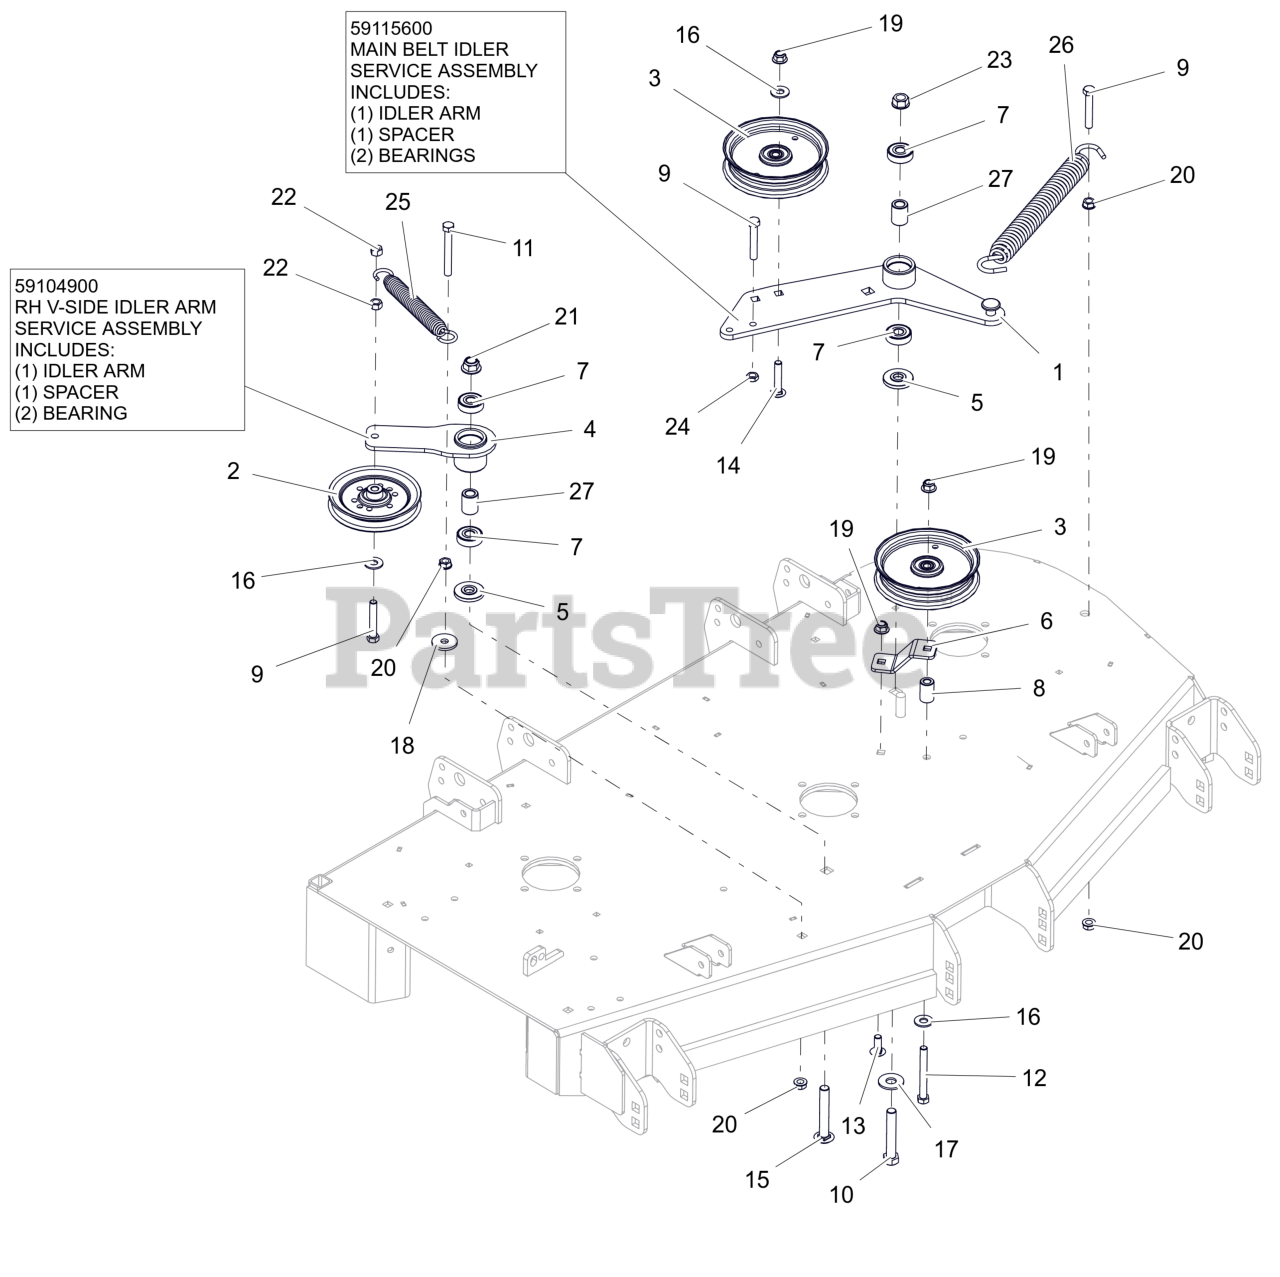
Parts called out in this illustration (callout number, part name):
1	WLDMT, DECK PTO IDLR ARM
1	ASSEMBLY, MAIN BELT IDLER
1	SPACER .510 X .867 X 1.1485
1	BRG-BALL .500X1.38X.437
2	IDLER, V, 5.00X.38
3	IDLER- FLAT - 5.00" X .75"
4	WLDMT, DECK RH IDLER ARM
4	RH V-SIDE IDLER ARM ASSEMBLY
4	SPACER .510 X .867 X 1.1485
4	BRG-BALL .500X1.38X.437
5	SPACER, IDLER ARM
6	PTO FIXED IDLER MTG BRKT -RED
7	BRG-BALL .500X1.38X.437
8	BUSHING, SLV .380X.750X1.190
9	BLT,HEX .38-16X2.25 G5 ZCC
10	BLT, HEX .50-13X3.00 G5 ZCC
11	BLT, HEX .38-16X3.00 G5 ZCC
12	BLT, HEX .38-16X3.25 G5 ZCC
13	BLT,RHSSN .38-16X1.00 G5 ZCC
14	BLT,RHSSN.375-16X2.00 G5 ZCC
15	BTL,RHSSN .500-13 X 3.25 G5 ZCC
16	WSHR,FLT .438X1.00X.083 ZCC
17	WSHR,FLT .563X1.375X.109 ZCC
18	WSHR,FLT .406X1.375X.135 ZCC
19	NUT,NYL-FLG .38-16 GF ZCC
20	NUT, SPNLK-FLG .38-16 G5 ZCC
21	NUT,NYL-FLG .50-13 GF ZCC
22	NUT-LK-CTR .38-16 ZC120
23	NUT-LK-CTR-FLG .500-13 GG ZCC
24	NUT-JAM .375-16 G2 ZCC
25	SPRING- EXTENSION
26	SPRING, EXTENSION
27	SPACER .510 X .867 X 1.1485
